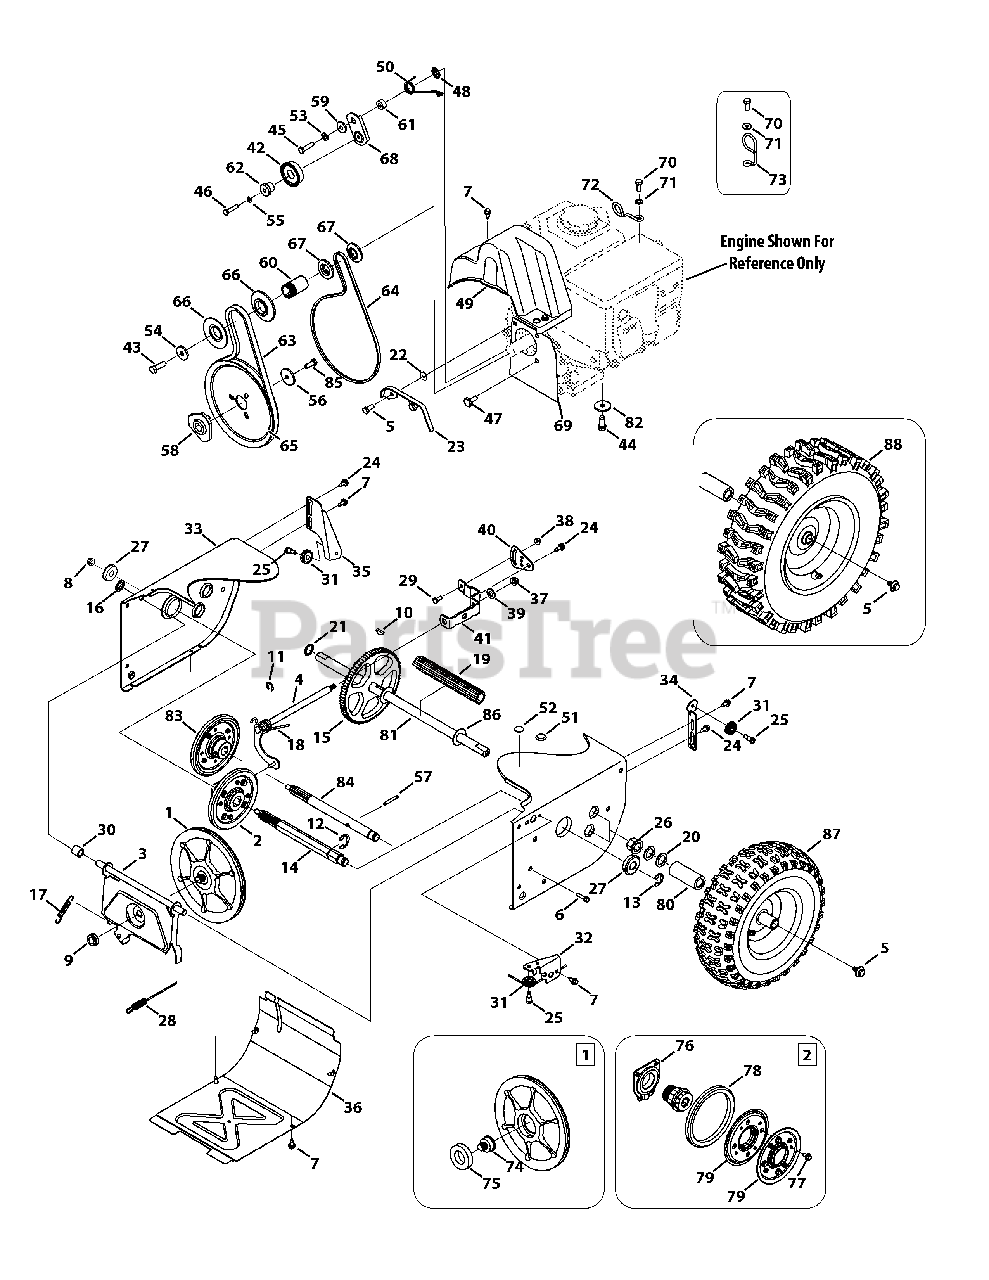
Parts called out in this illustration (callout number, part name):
1	Disc Assembly, Friction Wheel
2	Friction Wheel Assembly, 5.5 OD
3	Friction Wheel Support Bracket
4	Rod Shift Assembly
5	Screw, 5/16-24 x .750
6	Taptite Screw, 1/4-20 x 1.000
7	Taptite Screw, 1/4-20 x .625
8	Flange Lock Nut, 3/8-16
9	Flange Nut, 5/8-18
10	Hi-pro Key, 3/16 x 3/4 Dia.
11	E-Ring
12	Retaining E-Ring, .875 Dia.
13	E-Ring, .750 Dia.
14	Hex Shaft, 7-Tooth
15	Gear, 80-Tooth
16	Speed Nut, .500
17	Extension Spring
18	Torsion Spring, .750 x .968
19	Axle Spacer
20	Flat Washer, .793 x 1.24 x .060
21	Flat Washer, .75 x 1.00 x .060
22	Washer, Flat, .385 x .62 x .063
23	Belt Cover
24	Shoulder Screw, .368 x .113, 1/4-20
25	Shoulder Screw, 1/4-28, .340 x .355
26	Hex Flange Bearing
27	Ball Bearing, 17 x 40 x 12
28	Wheel Clutch Cable, 44.955"
29	Hex Head Screw, 1/4-20 x .620
30	Spacer, .508 ID x .75 OD x .68
31	Cable Roller
32	Auger Cable Front Guide Bracket
33	Frame
34	Auger Cable Guide Bracket
35	Drive Cable Guide Bracket
36	Frame Cover
37	Flange Lock Nut, 5/16-18
38	Flange Lock Nut, 1/4-20
39	Washer, Flat, .469 x .875 x .105
40	Speed Selector Pivot Bracket
41	Speed Selector Shift Bracket
42	Idler Pulley Assembly
43	Hex Screw, 3/8-24 x 1.25
44	Sems Screw, 3/8-16 x 1.00
45	Hex Screw, 5/16-24 x 1.25
46	Hex Screw, 1/4-20 x 1.25
47	Shoulder Screw, 5/16-24 x .5
48	Push-on Nut, .25 Dia.
49	Belt Cover, 4-Way lrg. block
50	Torsion Spring, .850 ID x .333
51	Plug, 3/8 ID
52	Plug, 1/2 ID
53	Lock Washer, 5/16
54	Flat Washer, .45 x 1.5 x .172
55	Washer, Lock, 1/4
56	Flat Washer, .34 x 1.50 x .150
57	Pin, Spirol, 2.5"
58	Adapter Pulley, .75 Dia.
59	Shoulder Spacer, .3175 x .5 x .0975
60	Spacer, .875 ID x 1.185 OD
61	Spacer, .340 x .750 x .330
62	Shoulder Space, .260 x .785 x .538
63	Auger Drive Belt, 4-Way lrg. block
64	Wheel Drive Belt, 4-Way lrg. block
65	Auger Drive Pulley, 8.1 x .5
66	Pulley Half, 2.600 OD
67	Pulley Half, 3/8 x 1.716 OD
68	Wheel Drive Idler Bracket
69	Cover Plate, 4-Way lrg. block
70	Hex Head Screw, 1.25 x 20
71	Washer, Flat, .330 x .630 x .0635
72	Cable Guide
73	Cable Guide
74	Friction Disc Bearing Pin
75	Ball Bearing, 30 x 55 x 13
76	Bearing Assembly
77	Taptite Screw, 5/16-18 x .750
78	Friction Wheel Rubber
79	Friction Wheel Plate
80	Spacer, 1.25 x .75 x 3.0
81	Axle, .75 x 22
82	Washer, Flat, .38 x 1.38 x .125
83	Friction Wheel Ass’y, Single-Speed
84	Shaft, Single-Speed
85	Hex Cap Screw, 5/16-24 x .875
86	Washer, Flat, .760 x 1.49 x .060
87	Snow Hog Wheel, 16 x 4.8
88	X-Trac Wheel, 16 x 4.8 x 8, LH
